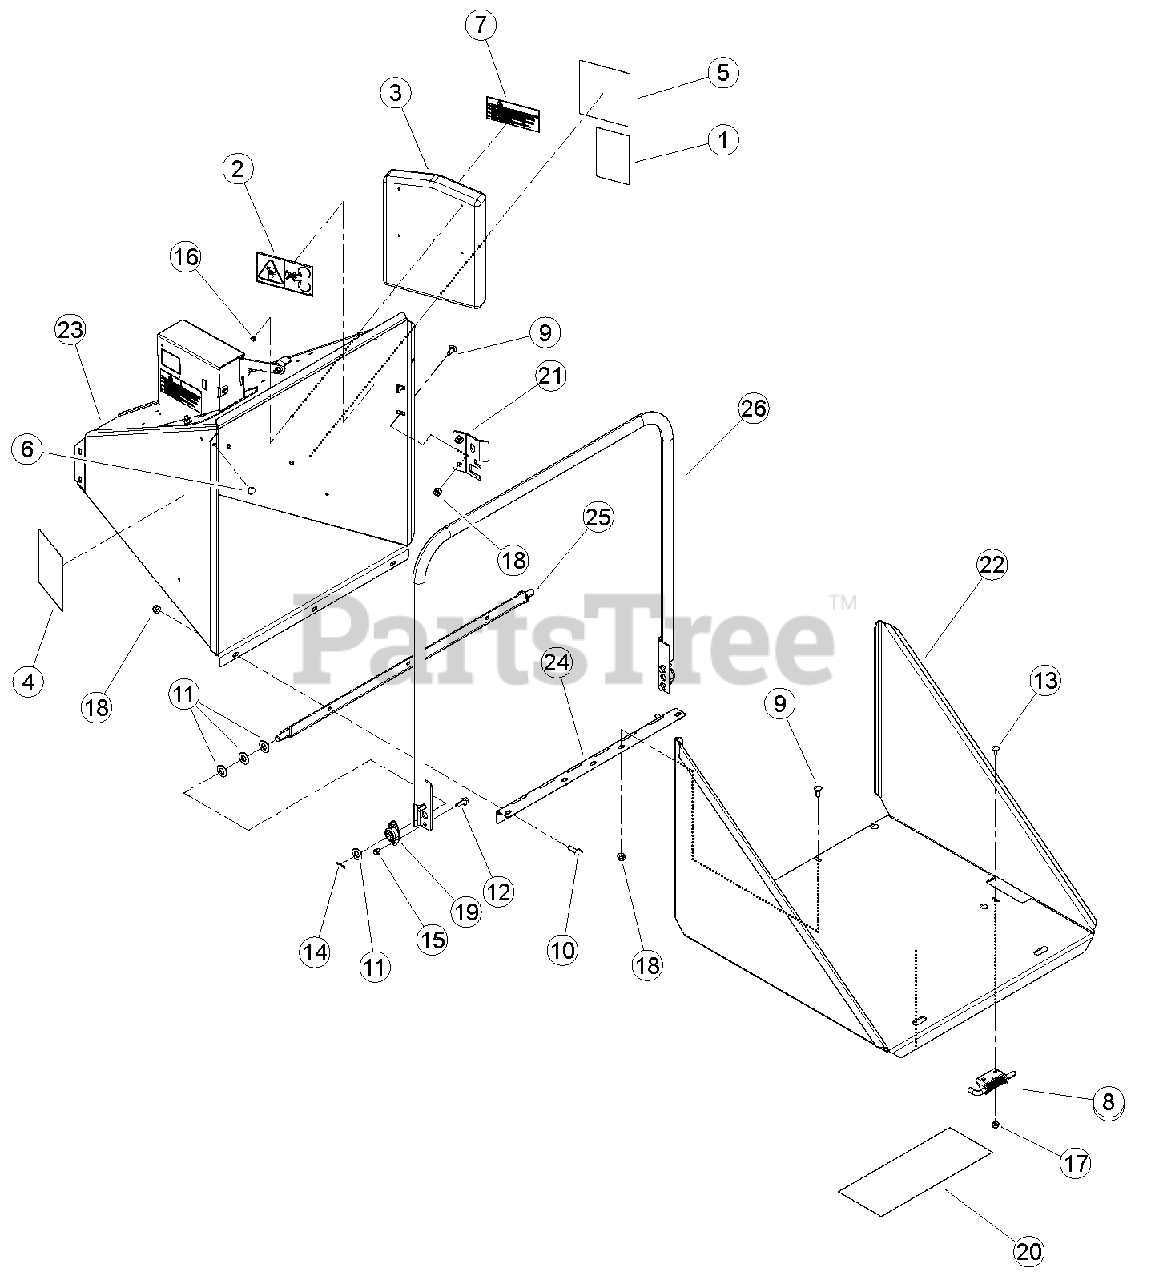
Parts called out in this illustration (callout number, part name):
1	DECAL, OPERATING INSTRUCTIONS ISO
2	DECAL, BLADE DANGER ISO
3	CONTAINER, INSTR. MANUAL
4	DECAL, FEED POSITION
5	DECAL, FEED POSITION
6	BUMPER, RUBBER
7	DECAL, MULTILINGUAL MANUAL
8	LATCH, RH HINGE
9	BOLT, 3/8 X 1" CRG GR5 NC ZP
10	BOLT, 3/8 X 1-1/4 FLANGE NC
11	WASHER, 5/8" SAE FLAT ZP
12	BOLT, 3/8 X 1 FLANGE NC
13	BOLT, 5/16 X 3/4 GR5 CRG NC ZP
14	PIN, 1/8 X 1.00 ZP COTTER
15	NUT, 3/8" NE NYLOCK ZP
16	RIVET, 1/4 X 1/2 DOME HD BLIND SS
17	NUT, 5/16-18 NYLOCK-FLANGE
18	NUT, 3/8-16 NYLOCK FLANGE
19	BEARING, SIDE FLANGE MOUNT 5/8"
20	DECAL, BEARCAT WEB
21	PLATE, TRAY STOP
22	WELDMENT, 5" CHIPPER TRAY
23	WELDMENT, 5" CHIPPER CHUTE
24	HINGE, EXTENSION TRAY
25	WELDMENT, CONTROL PIVOT
26	WELDMENT, CONTROL ARM
